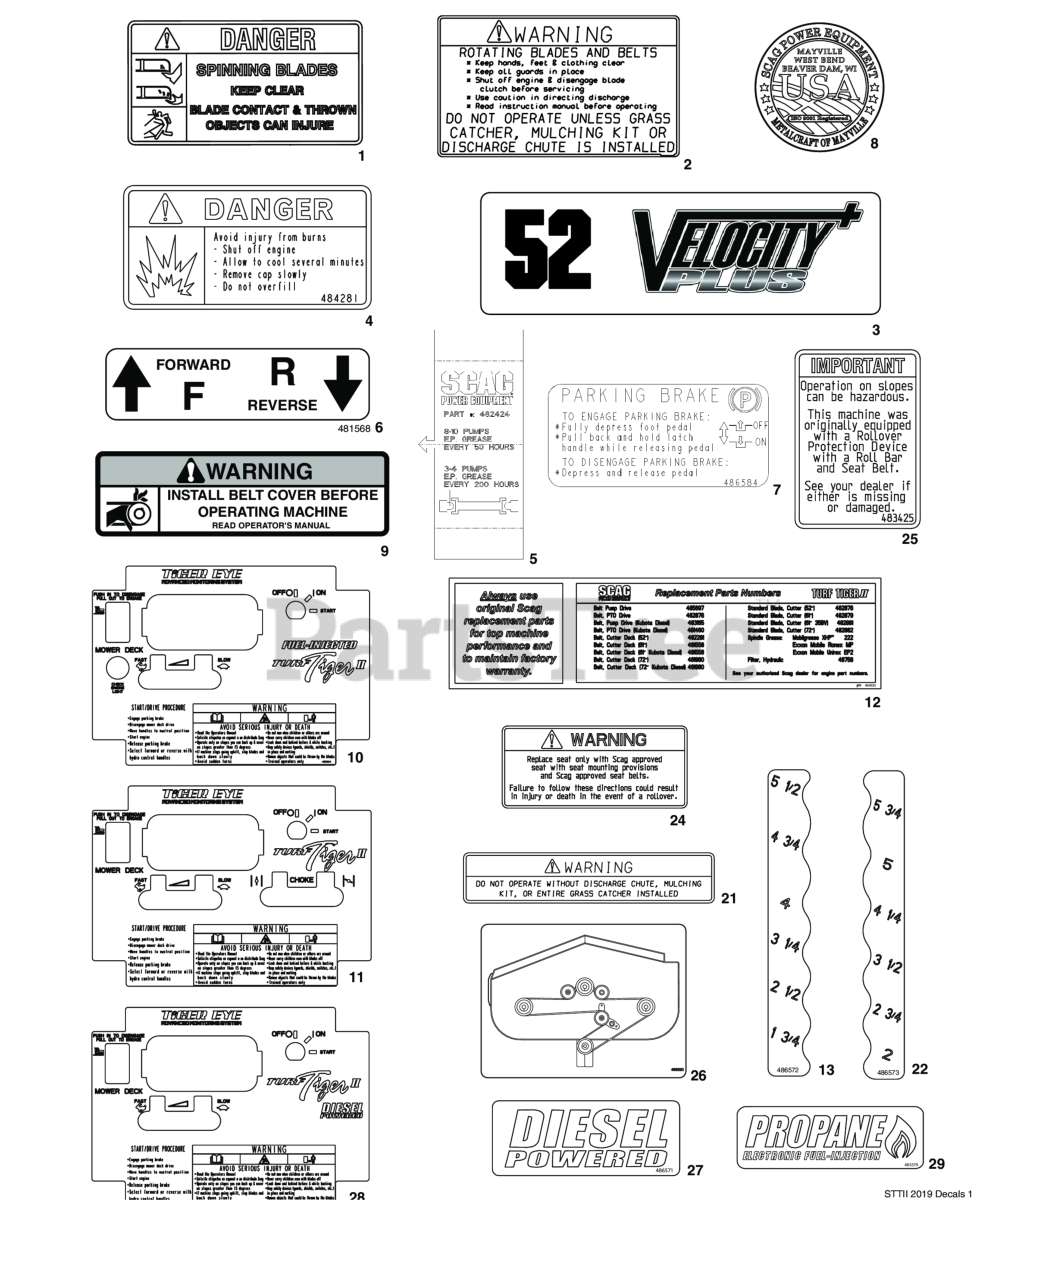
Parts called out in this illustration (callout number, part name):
1	Decal, Danger-Spinning Blades
2	Decal, Warning - Rotating Blades
3	Decal 52V 483201 Decal 61V
4	Decal, Fuel Tank - Gasoline Engines
5	Decal, Driveshaft
6	Decal, Traction Control
7	Decal, Parking Brake
8	Decal, Metalcraft - USA
9	Decal, Warning - Belt Cover
10	Decal, Instrument Panel - Fuel Injected
11	Decal, Instrument Panel
12	Decal, STTII Replacement Parts
13	Decal, Cutting Height - LH
21	Decal, Warning-Discharge
22	Decal, Cutting Height - RH
24	Decal, Seat Replacement
25	Decal, ROPS
26	Decal, Belt Routing
27	Decal, Diesel Powered - Kubota Diesel
28	Decal, Instrument Panel - Kubota Diesel
29	Decal, Propane - Kohler LP-EFI
